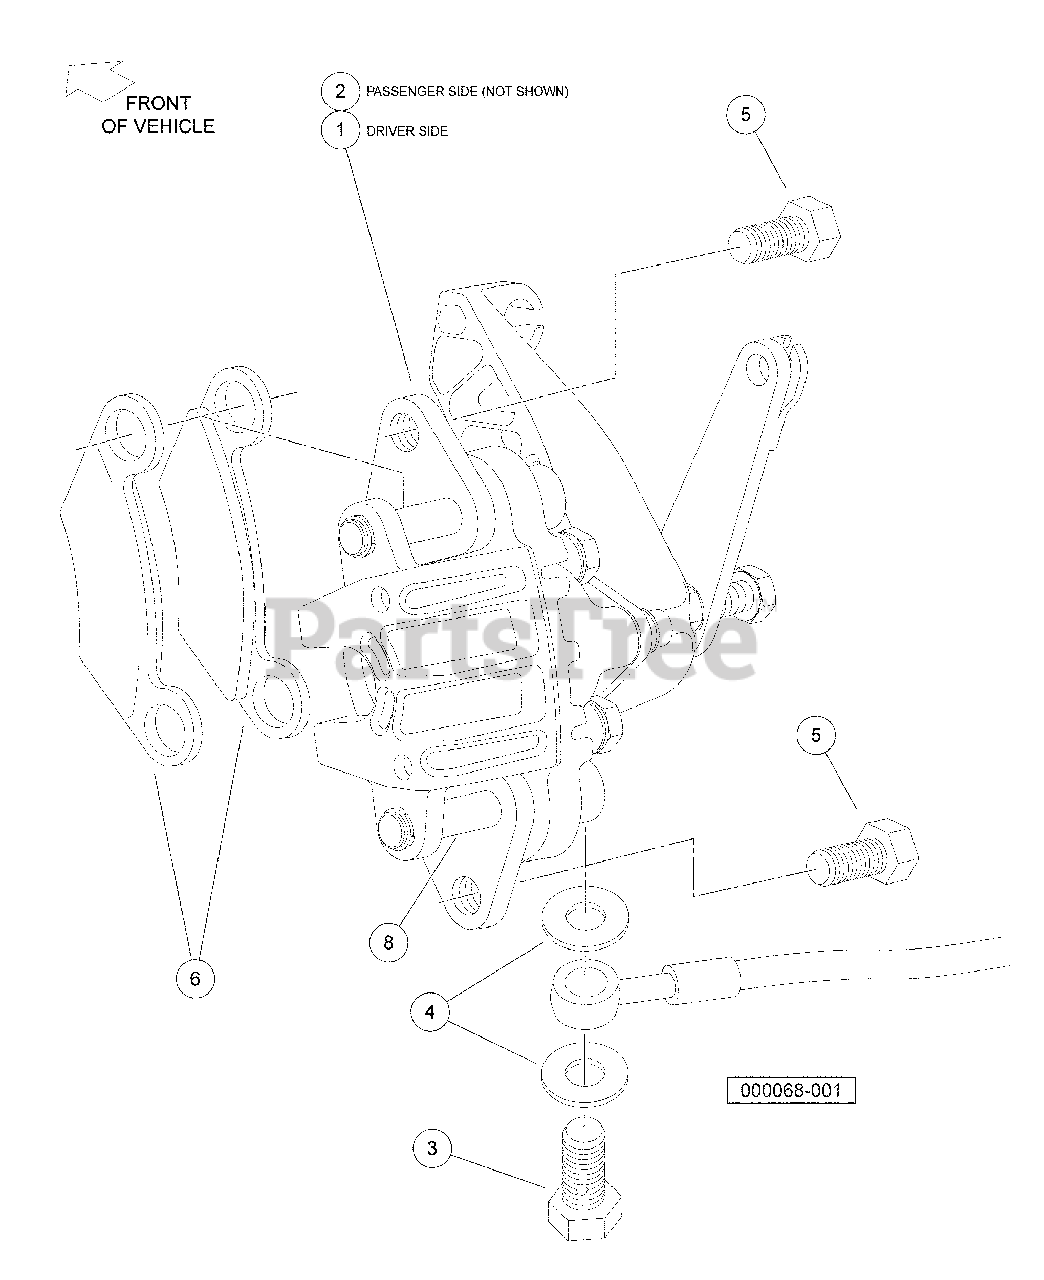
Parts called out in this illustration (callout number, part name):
1	Caliper, Brake, Hydro-Mechanical, LH
2	Caliper, Brake, Hydro-Mechanical, RH
3	Bolt, Banjo, M10x1x19
4	Washer, Copper, M10 Crush
5	Bolt Flange Head, 3/8-24x.750 with Loctite
6	Service Kit, Brake Pad (4 Pads)
7	Spring, Brake Caliper Return
8	Pin, Slide, 7/16
